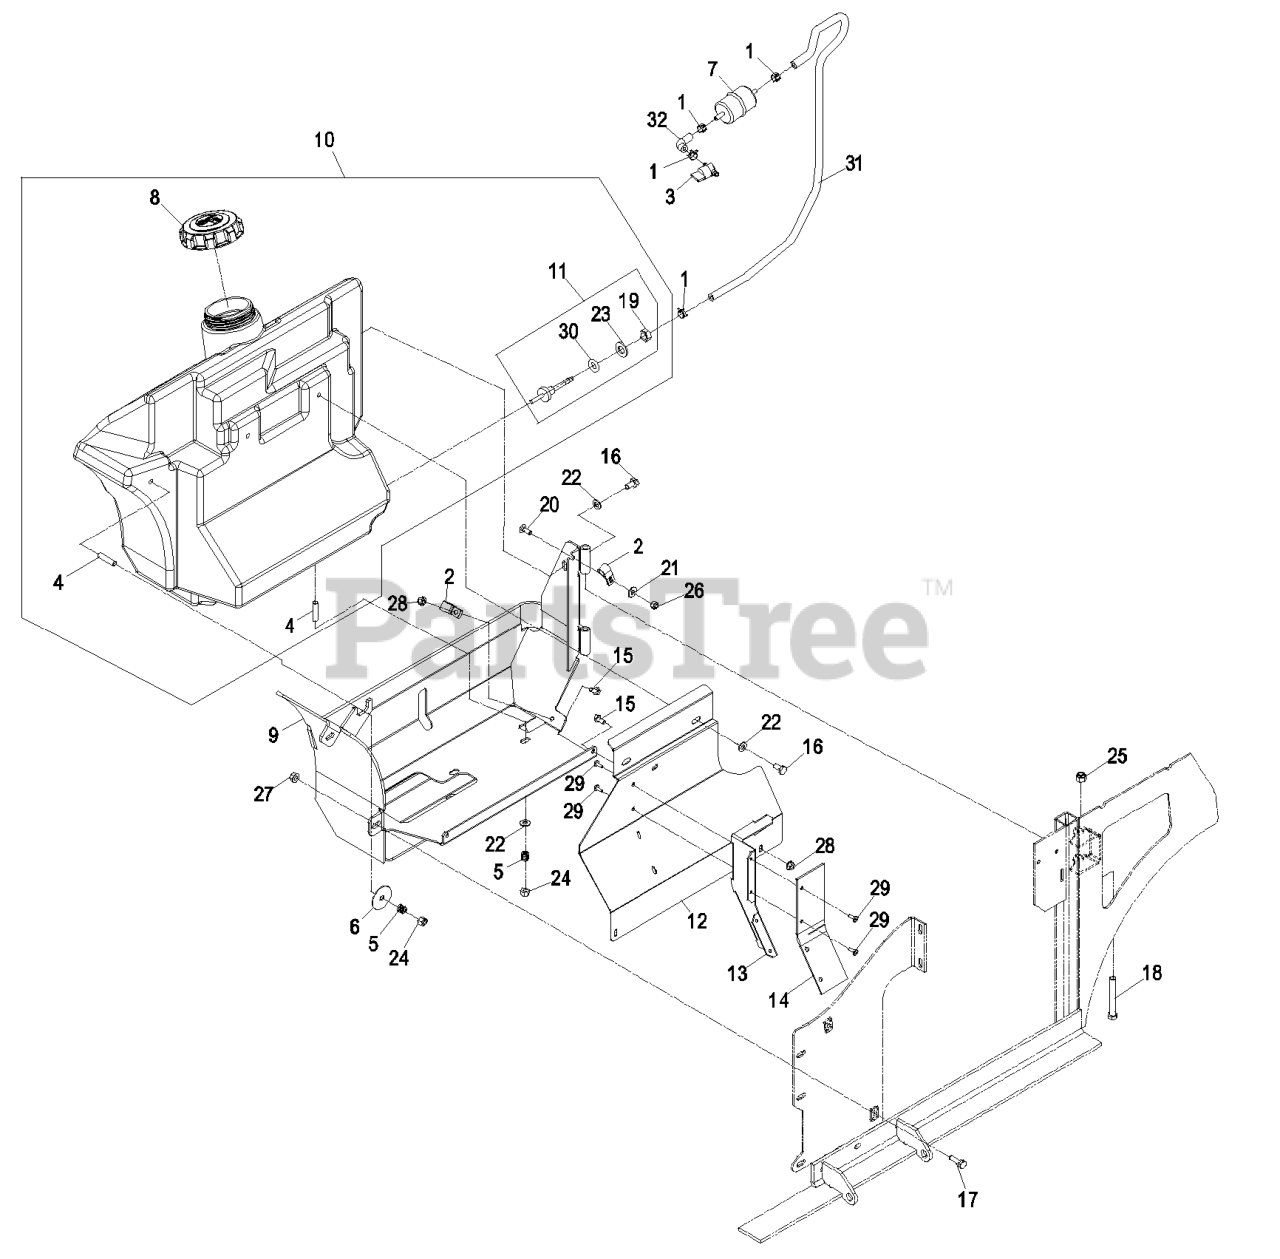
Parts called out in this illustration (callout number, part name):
2	CLIP-LOOM
3	VALVE-FUEL
4	STUD
5	SPRING-TANK, FUEL
7	Kohler Part No. 2405010 Fuel Filter
8	CAP-FUEL, GAS
10	ASM,FUEL TANK W/CAP
11	FITTING-FUEL, BULKHEAD
12	Panel, Tank Shield
13	DEFLECTOR-AIR
14	FLAP-RUBBER
15	SCREW-HH
16	SCREW-HH
17	SCREW-HH
18	SCREW-CARR
19	NUT-JAM
20	BOLT-CARR
21	WASHER-FLAT
22	WASHER-PLAIN
23	WASHER-FLAT
24	NUT-LOCK, NI
25	NUT-LOCK, NI
26	NUT-LOCK, NI
29	RIVET-BLIND
30	O-RING,BULKHEAD FITTING
31	HOSE-FUEL
32	HOSE-FUEL
